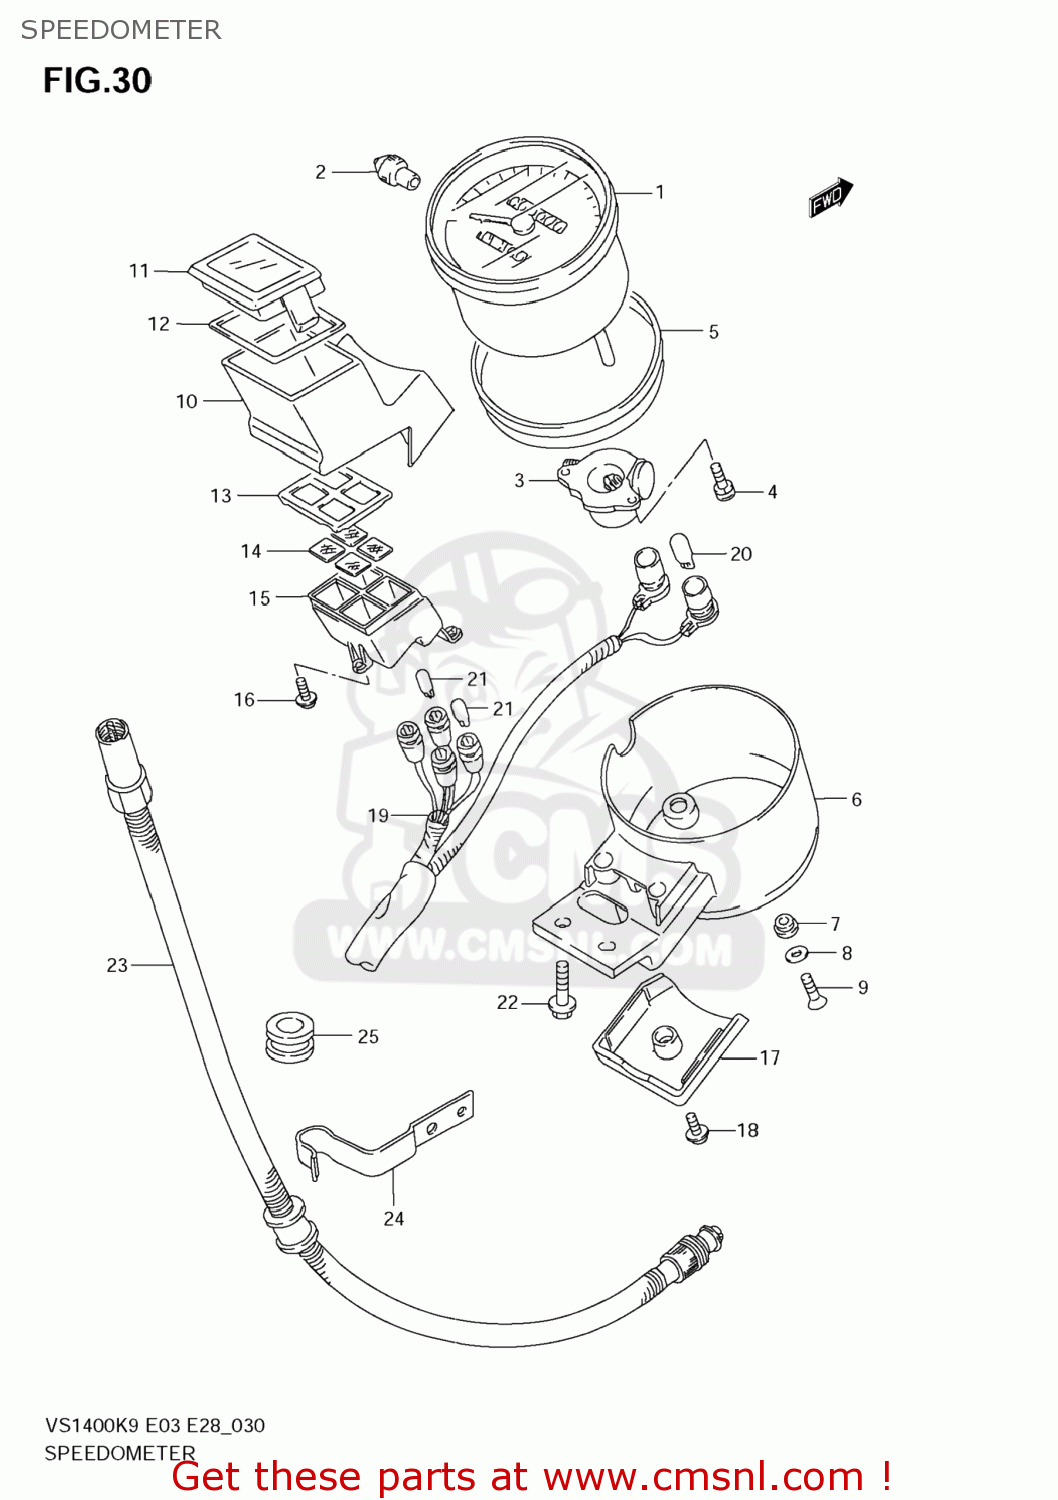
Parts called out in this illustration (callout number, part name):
1	SPEEDOMETER(KILO)
2	KNOB,TRIP
3	BOX,GEAR
4	SCREW
5	CUSHION
6	COVER,METER
7	CUSHION,METER
8	WASHER
9	SCREW
10	BOX,PILOT
11	LENS,PILOT BOX
12	CUSHION
13	PLATE,PILOT LENS
14	LENS SET,PILOT LAMP
15	CASE,PILOT LAMP
16	SCREW
17	COVER,PILOT BOX
18	SCREW
19	SOCKET,METER
20	BULB(12V3.4W,T10)
21	BULB(12V1.7W,T6.5)
22	SCREW
23	CABLE ASSY,SPEEDOMETER
24	GUIDE,SPEEDOMETER CABLE
25	GROMMET
